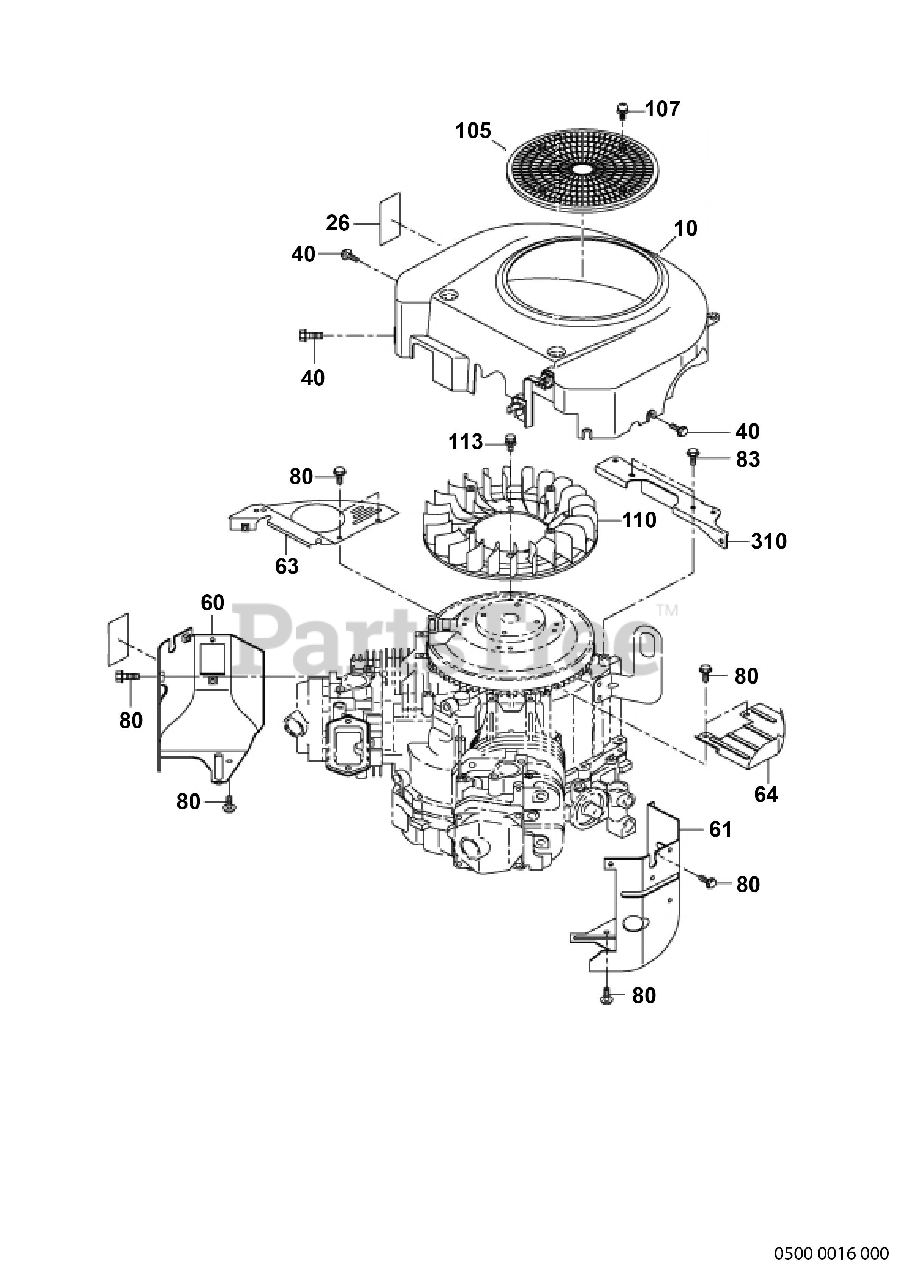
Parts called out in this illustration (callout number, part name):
10	BLOWER HOUSING UN
26	LABEL(WARNING)
60	CYLINDER BAFFLE 1 CP
61	CYLINDER BAFFLE 2 CP
63	CYLINDER BAFFLE 4 UN
64	CYLINDER BAFFLE 5
105	ROTATING SCREEN
107	SCREW AND WASHER
110	COOLING BLOWER UN
113	BOLT AND WASHER
310	SUPPORT,B,HOUSING
